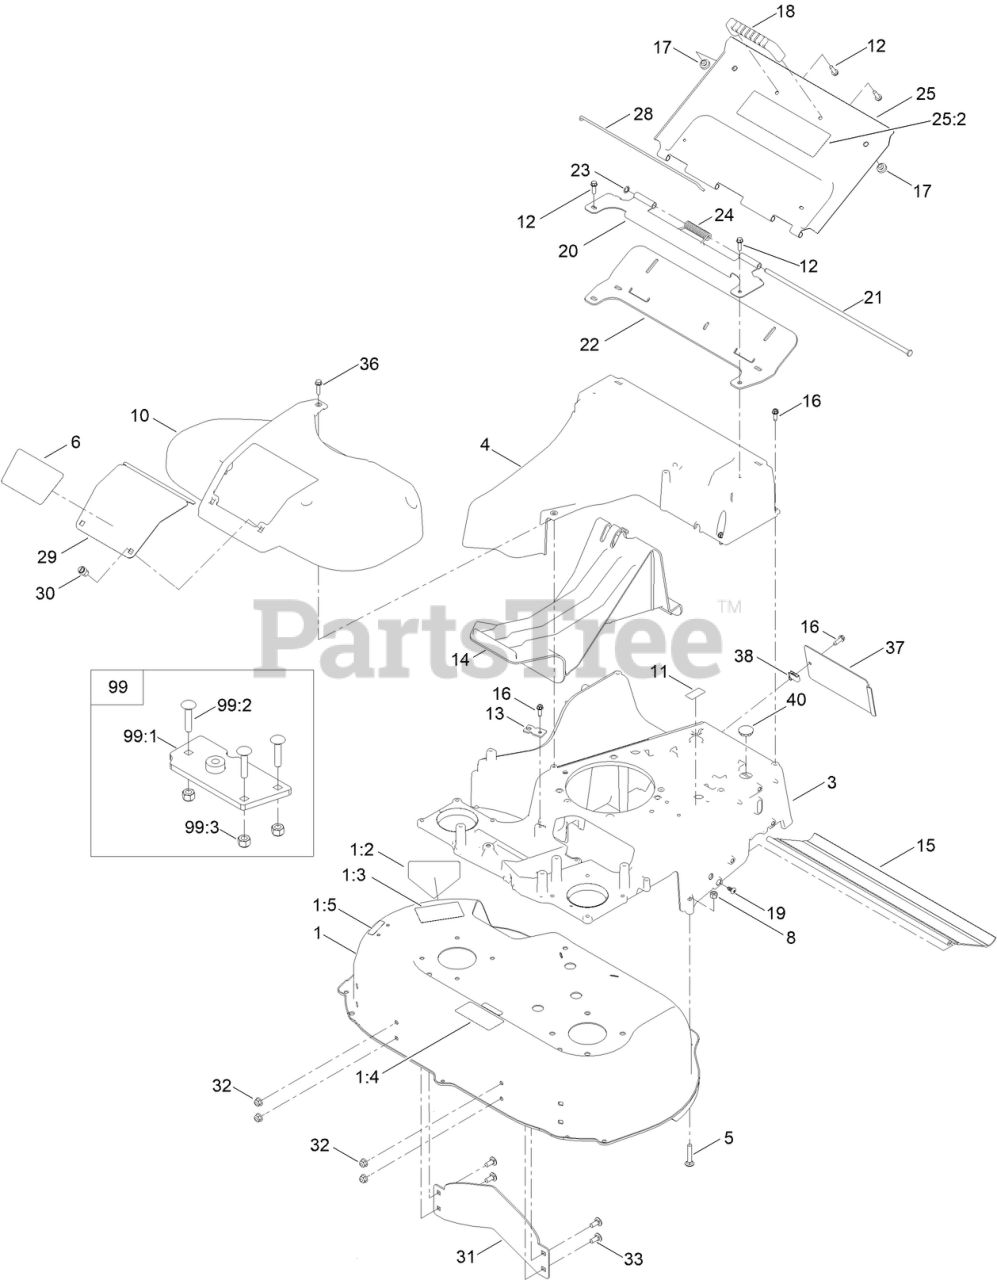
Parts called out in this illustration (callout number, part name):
1	DECK ASM
1:2	DECAL-DANGER
1:3	DECAL-DANGER, CE
1:5	DECAL-WARNING
3	FRAME-30 INCH
5	BOLT-CAR
6	DECAL-30 INCH
8	NUT-LOCK, NI
10	COVER-BELT
11	DECAL-PATENT
12	SCREW-HWH
13	BRACKET-CABLE, TRACTION
14	PLUG-MULCH
15	SHIELD-TRAILING
16	SCREW-HWHTF
17	BUMPER
18	HANDLE-DOOR
19	SCREW-PTH
20	BRACKET-HINGE
21	PIN-HINGE
22	SEAL-DOOR
23	RING-RETAINING
24	SPRING-TORSION, COVER
25	REAR DOOR ASM
25:2	DECAL-WARNING
28	CLIP-SEAL
29	DOOR-ACCESS
30	FASTENER
31	BAFFLE-CONTROL
32	NUT-HF, NI
33	SCREW-CARR
36	SCREW-HWHTF
37	COVER-FRAME
40	PLUG-BUTTON
99	FRAME PLATE KIT
99:1	PLATE-FRAME
99:2	SCREW-CARR
99:3	NUT-LOCK, NI
